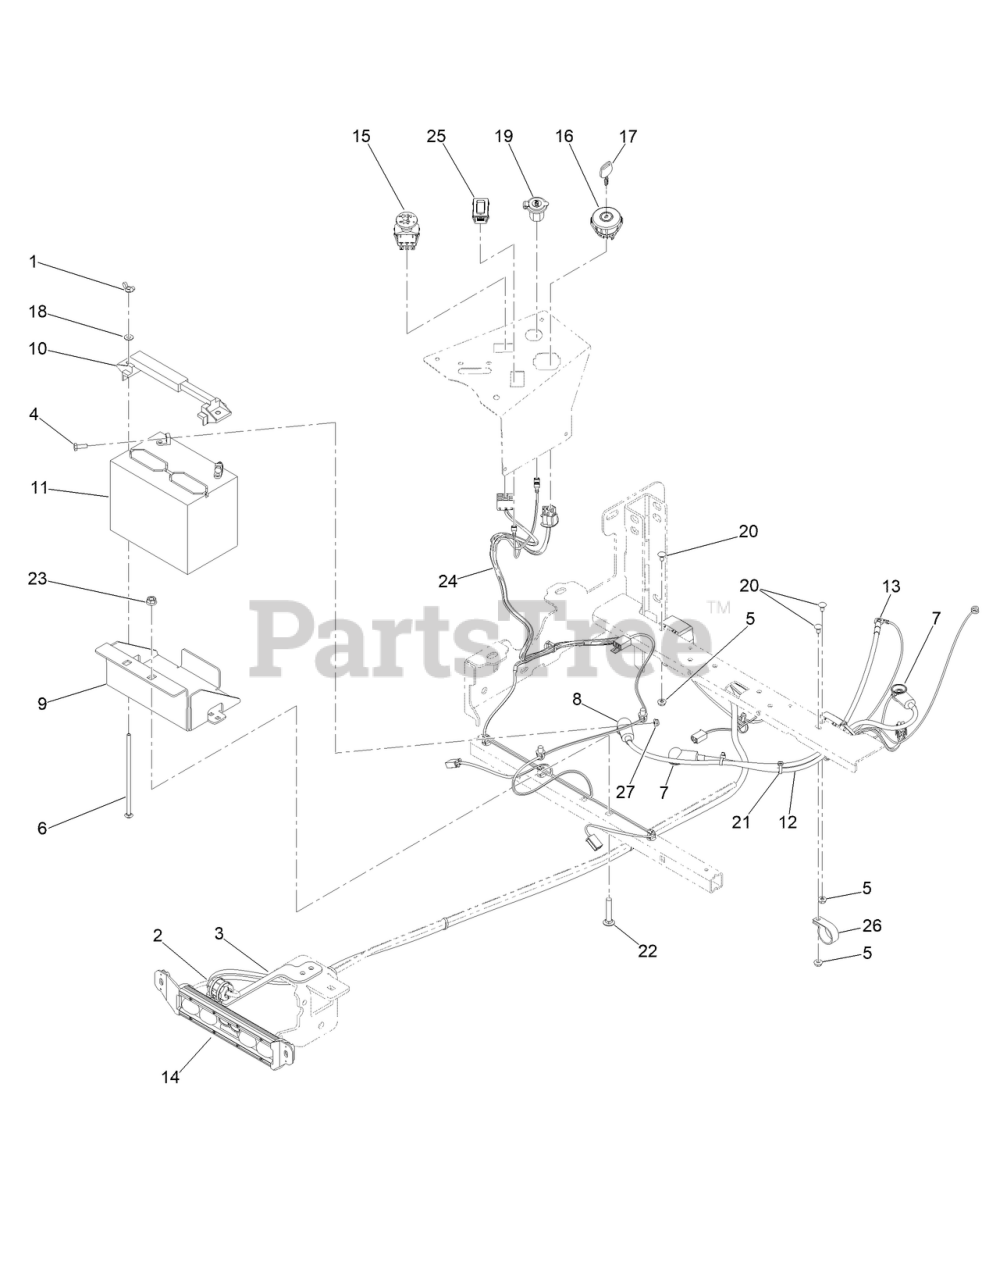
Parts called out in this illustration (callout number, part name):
1	NUT-WING
2	FAIR-RITE ROUND CABLE SNAP-IT SIZE B
3	FAIR-RITE BRACKET PAINTED
4	SCREW-HH
5	1/4-20 HEX FLANGE NUT
6	1/4-20 X 7 CARRIAGE BOLT ZINC
7	3.15 LGTH STRAIGHT INSUL TERM COVER RED
8	STRAIGHT INSULATING TERMINAL COVER
9	MWR BATTERY BOX
10	BATTERY HOLD DOWN
11	12 VOLT START BATTERY 300CCA
12	MWR POSITIVE BATTERY CABLE 25IN
13	MWR NEGATIVE CABLE 28
14	FULL BEAM WITH LIGHTED HELMET LIGHT BAR
15	PTO SWITCH
16	IGNITION SWITCH
17	2023 MWR KEY
18	WASHER-FLAT
19	12 VOLT AUXILLIARY PLUG
20	SCREW-CARR
21	TIE-CABLE
22	SCREW-CARR
23	3/8-16 HEX FLANGE NUT W/SERR ZINC YELLOW
24	HARNESS-WIRE
25	HOUR METER
26	1-1/4IN CUSHIONED LOOP CLAMP BLACK
27	NUT-HF
